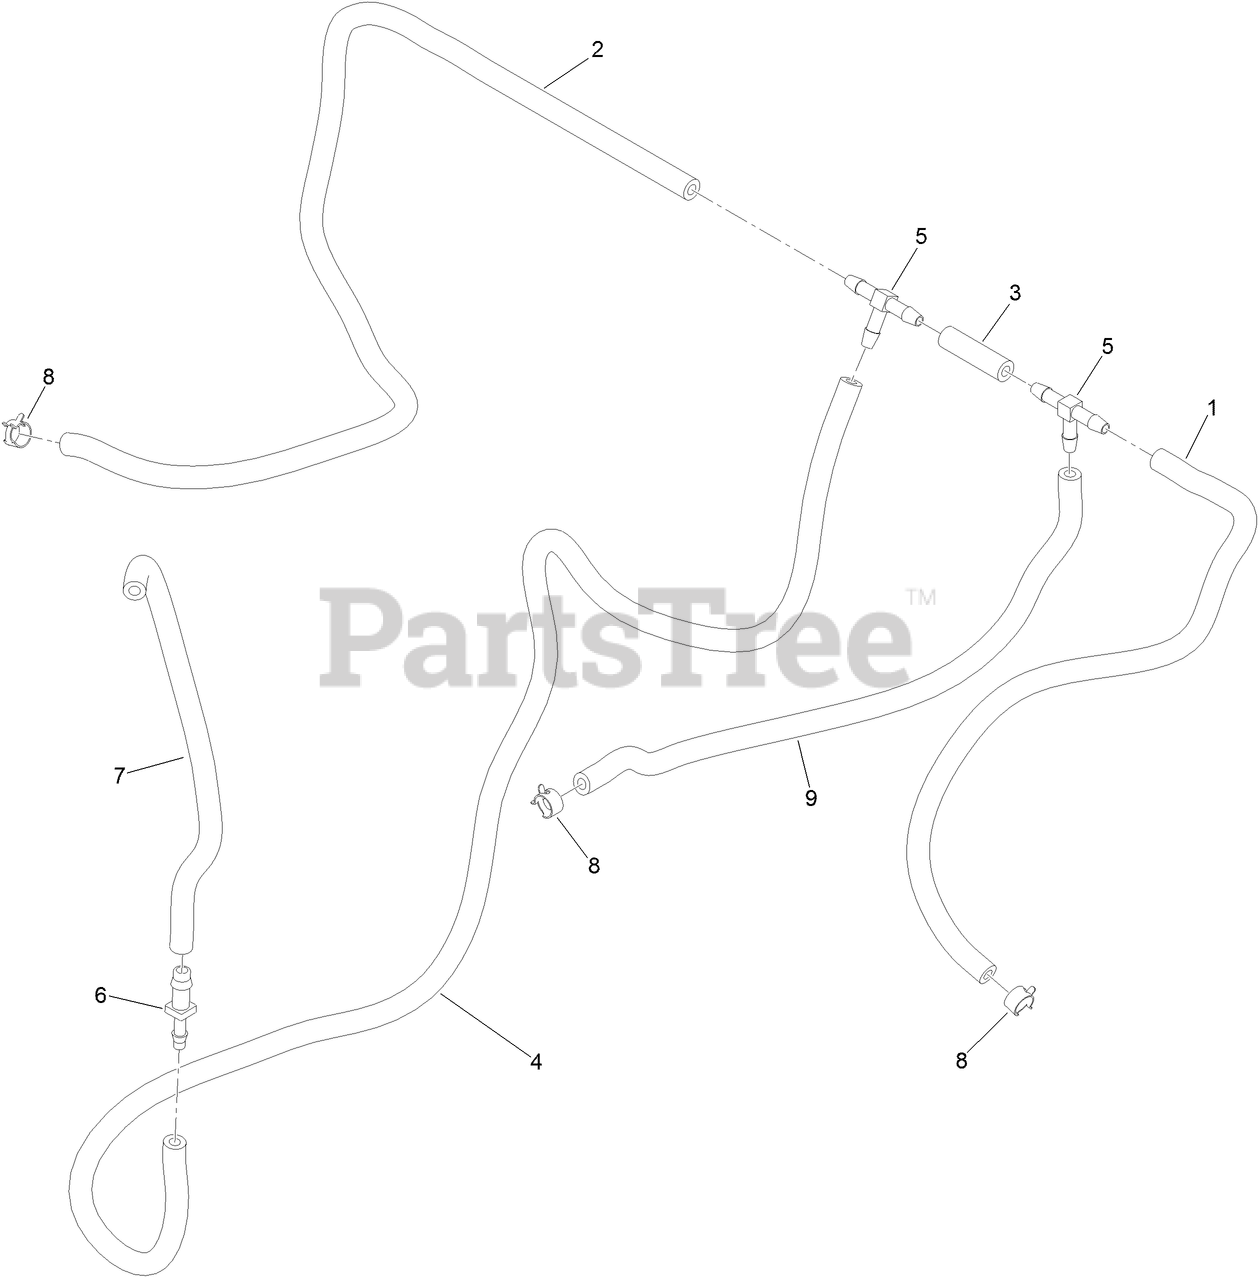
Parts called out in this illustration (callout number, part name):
1	HOSE-FUEL
2	HOSE-FUEL
3	HOSE-FUEL
4	HOSE-FUEL
5	FITTING-TEE, BARBED
6	FITTING-STRAIGHT
7	HOSE-FUEL
8	CLAMP-HOSE
9	HOSE-FUEL
